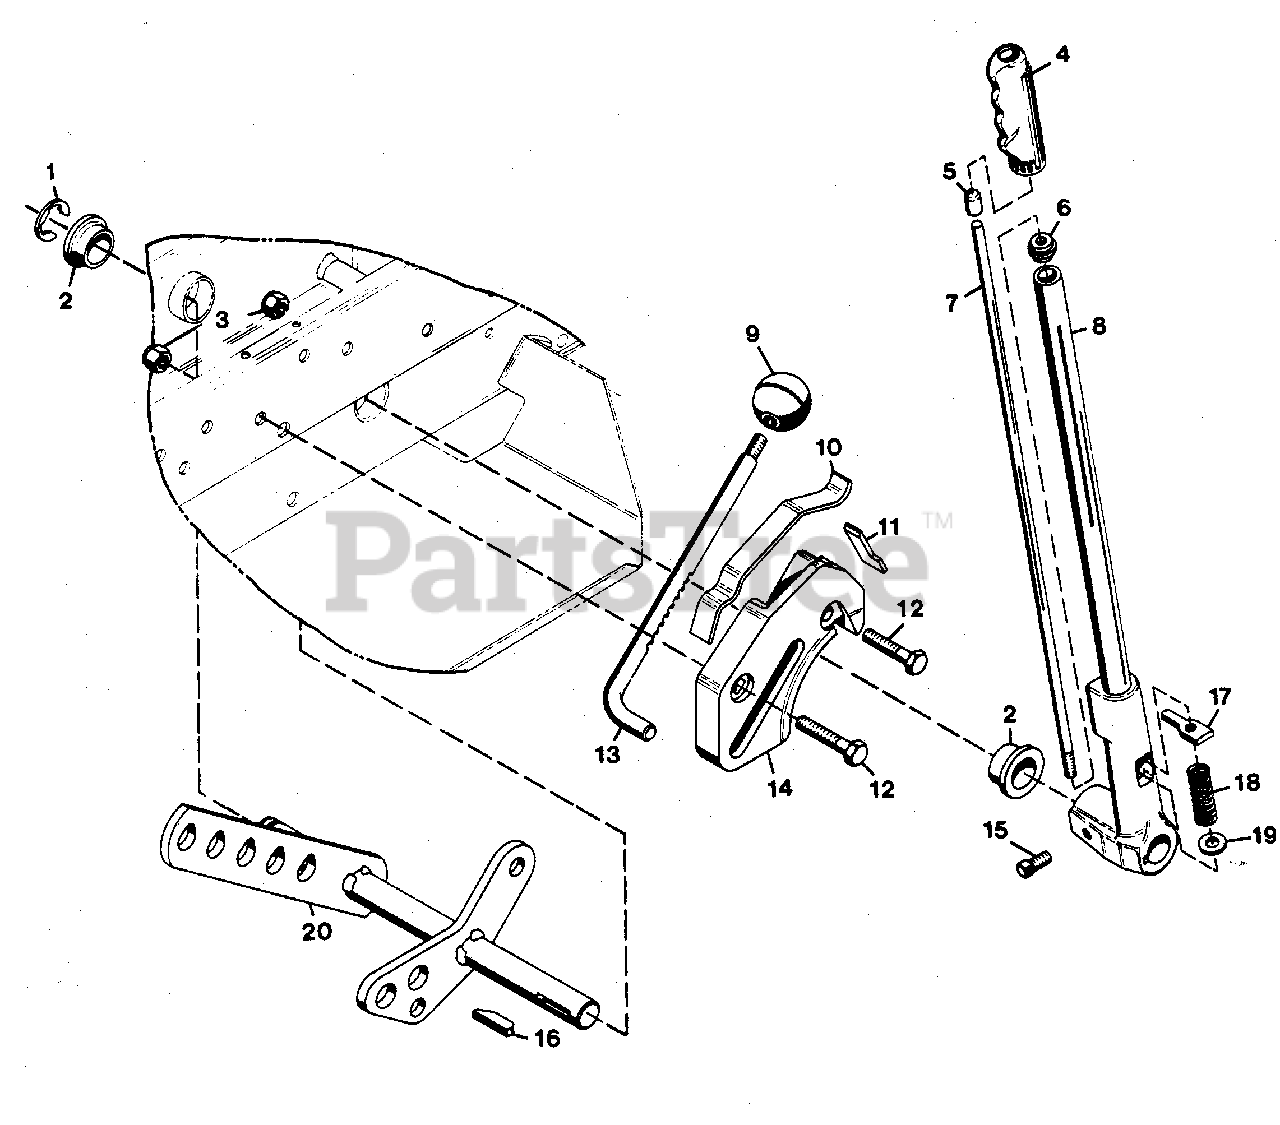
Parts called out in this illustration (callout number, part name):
1	GRIP, FLEX
2	GUIDE, PUSH ROD
3	ASSEMBLY, LEVER LIFT
4	TIP, PUSH ROD
5	ROD, LEVER PUSH
6	E-RING, 1.000 SHAFT
7	BUSHING, PIVOT
8	SHAFT, LIFT LEVER WELDMENT
9	KNOB, CONTROL
10	SPRING, STOP
11	STOP, LEVER
12	CASTING, LOCATOR
13	KEY, WOODRUFF .250X2.125 SOFT
14	NUT, LOCK 3/8-16
15	ROD, LEVER STOP
16	BOLT, HEX 3/8-16X1.25
17	SCREW, SET 3/8-16X.50 HSCP
18	PAWL, LEVER
19	SPRING, COMP. 2X.720X15.5 LB/IN
20	WASHER, SPECIAL FLAT .45X.99X.10
